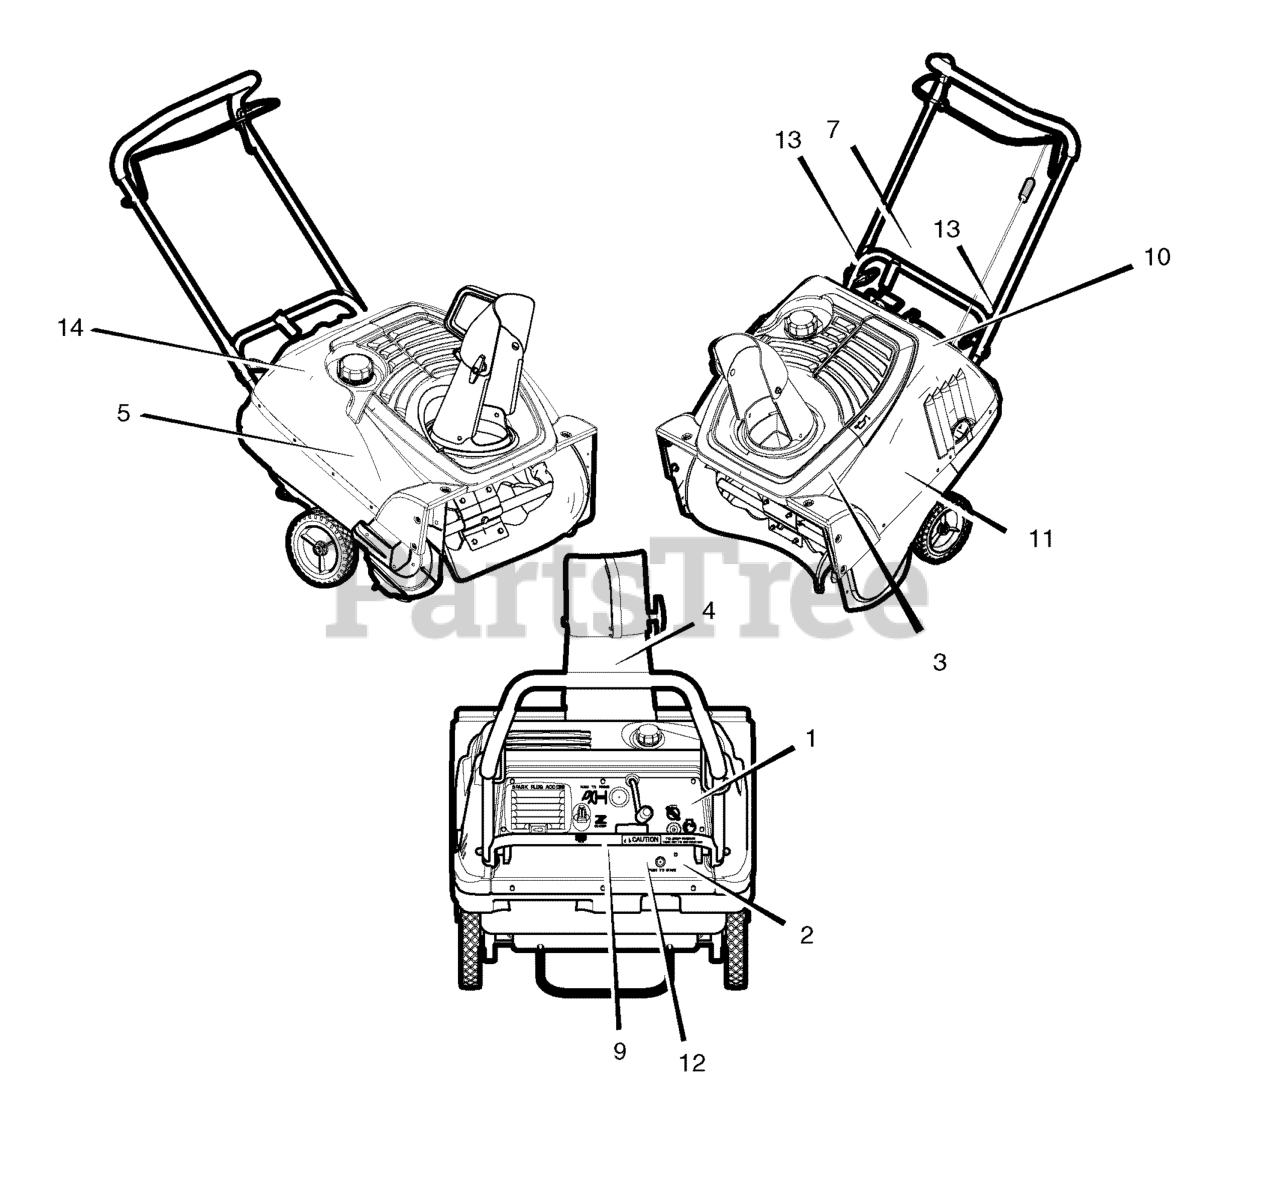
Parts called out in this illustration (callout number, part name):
1	Decal, Panel - 22" ES CANADA
2	Decal, Push To Start
3	Decal, Danger Auger
4	Decal, Danger Chute
5	Decal, 22" CRAFTSMAN LOGO
7	Decal, Auger Control
9	Decal, Electric Plug Orientation
10	Decal, Warning, Access Cover
11	Decal, 22" Craftsman Logo Model Info
12	Decal, Choke
13	Decal, Handle Protector
14	Decal, Briggs & Stratton
